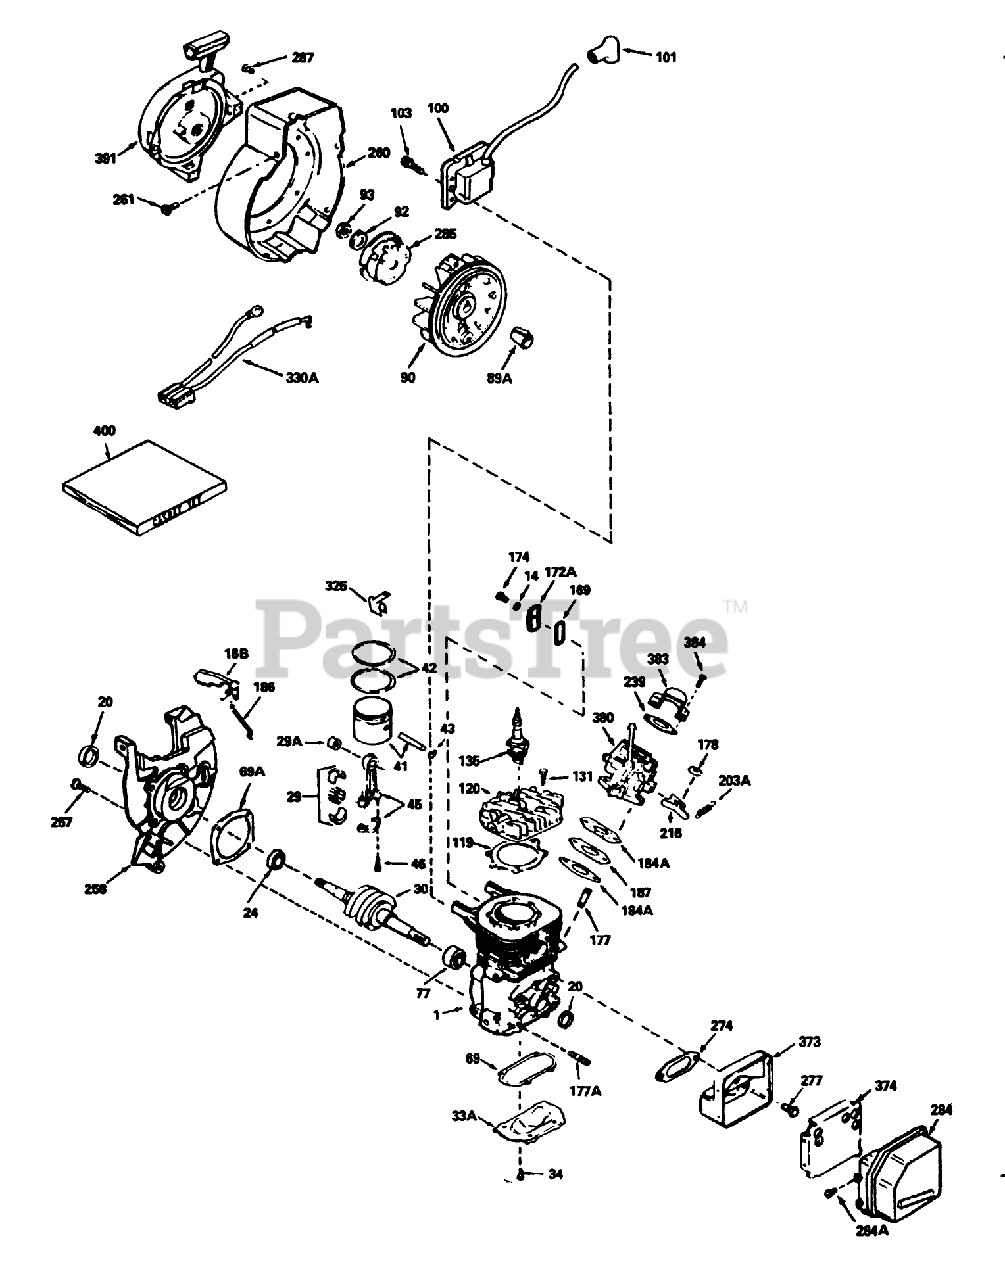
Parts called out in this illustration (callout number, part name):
1	Block Ass-y-Cylinder (Order short block if replacement is required)
14	Washer
16B	Vane-Air
20	Seal-Oil
24	Bearing-Ball
29	Needle Bearing and Liner Set (37 Needles)
29A	Bearing-Cartridge
30	Crankshaft
33A	Plate-Cover
34	Screw (T-25, 10-24 x 1/2)
41	Piston (Incl. Ref. #43)
42	Ring Set
43	Ring-Retaning
45	Rod Assy.-Connecting (Incl. Ref. #3, 3A 3B)
46	Bolt-Rod, Connecting
69	Gasket-Plate, Cover
69A	Gasket-Cover, Cylinder
77	Bearing-Cartridge
89A	Blade (20 inch)
90	CARB BODY S
92	Washer-Belleville
93	Nut-Flywheel
100	Solid State
101	Cover-Spark Plug
103	Screw
119	Gasket-Head, Cylinder
120	Head-Cylinder
131	Screw (T-30, 1/4-20 x 3/4)
135	Spark Plug-Resistor (R C J 8Y)
169	Cover-Compression, Release
172A	Comp. Release Cover
174	Screw (T-25, 10-24 x 1/2)
178	Locknut
184A	Gasket-Carburetor
186	Link-Governor
187	Spacer
203A	Spring-Governor
216	Lever-Adjusting, Rpm
239	2060A77 WIZARD ROTA
257	Screw (T-30, 1/4-20 x 5/8)
258	Base Ass-y-Blower Housing (Incl Ref. #20)
260	Housing-Blower
261	Screw (1/4-20 x 1/2)
274	Gasket-Exhaust
277	Screw (T-30, 1/4-20 x 5/8)
284	Cover-Muffler
284A	Screw
285	Cup-Starter
287	Rivet-Pop
325	Clip-Wire
330A	Harness-Wire
373	Base-Muffler
374	Baffle-Muffler
380	Carburetor (Incl. Ref. #184A)
383	Baffle-Carburetor
384	Screw
391	Starter-Rewind
400	Gasket Set
